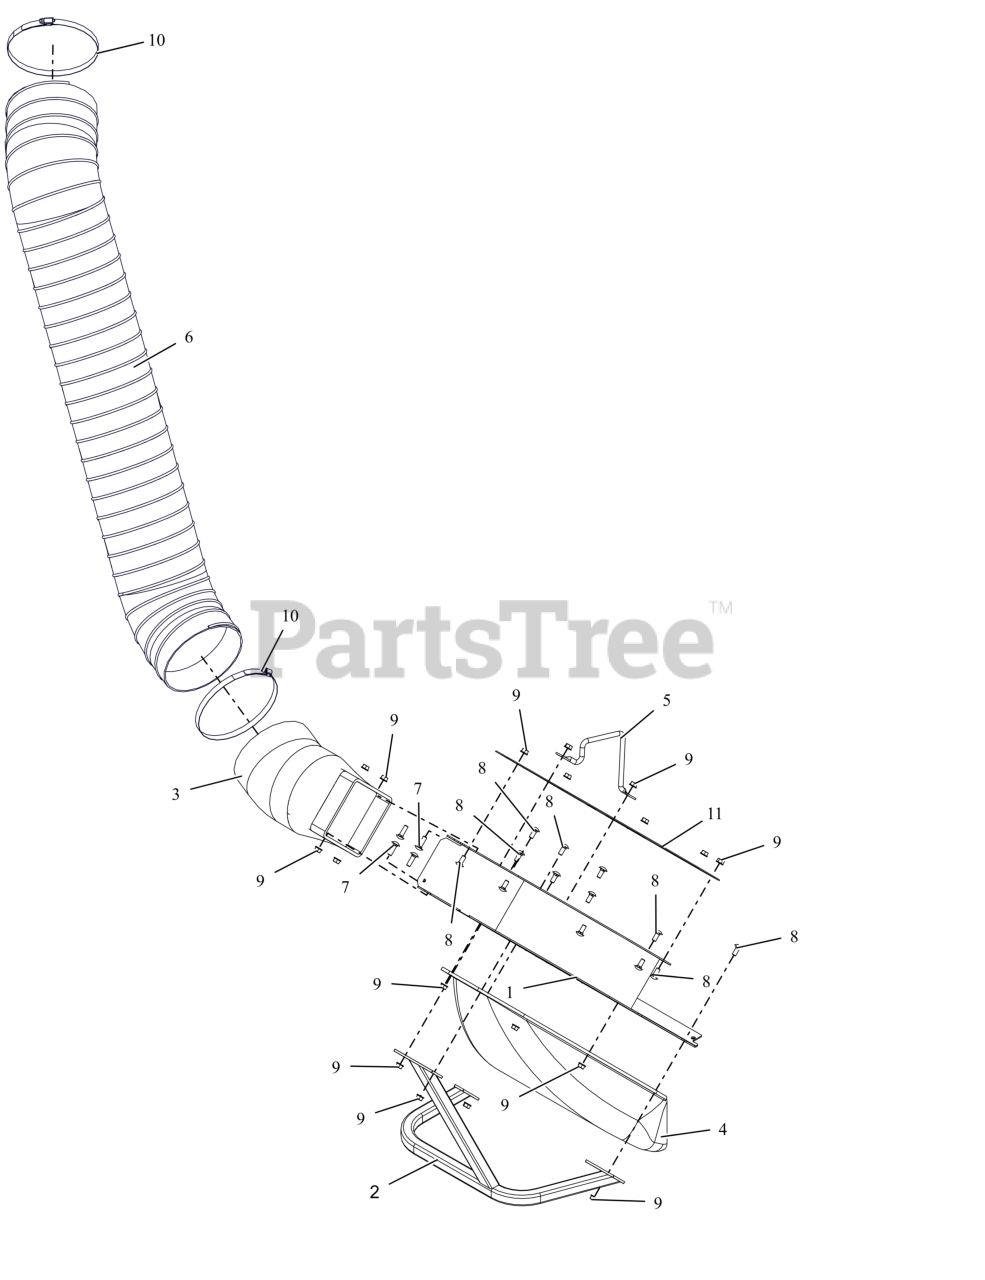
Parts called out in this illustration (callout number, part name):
1	WLDMT, HOUSING SCROLL (BLACK)
2	WLDMT, BLOWER GUARD (BLACK)
3	ADAPTER, HOSE
4	PLENUM, GRASS PUMP
5	HANDLE, BOLT-ON
6	HOSE, FLEXIBLE-56"
7	BLT,RHSSN .31-18X1.00 G5 ZCC
8	BLT, RHSSN.31-18X.750 G5 ZCC
9	NUT-LK-TOP-FLG .312-18 GF ZCC
10	CLAMP, 7' BAGGER HOSE
11	PLT, BLOWER COVER (BLACK)
